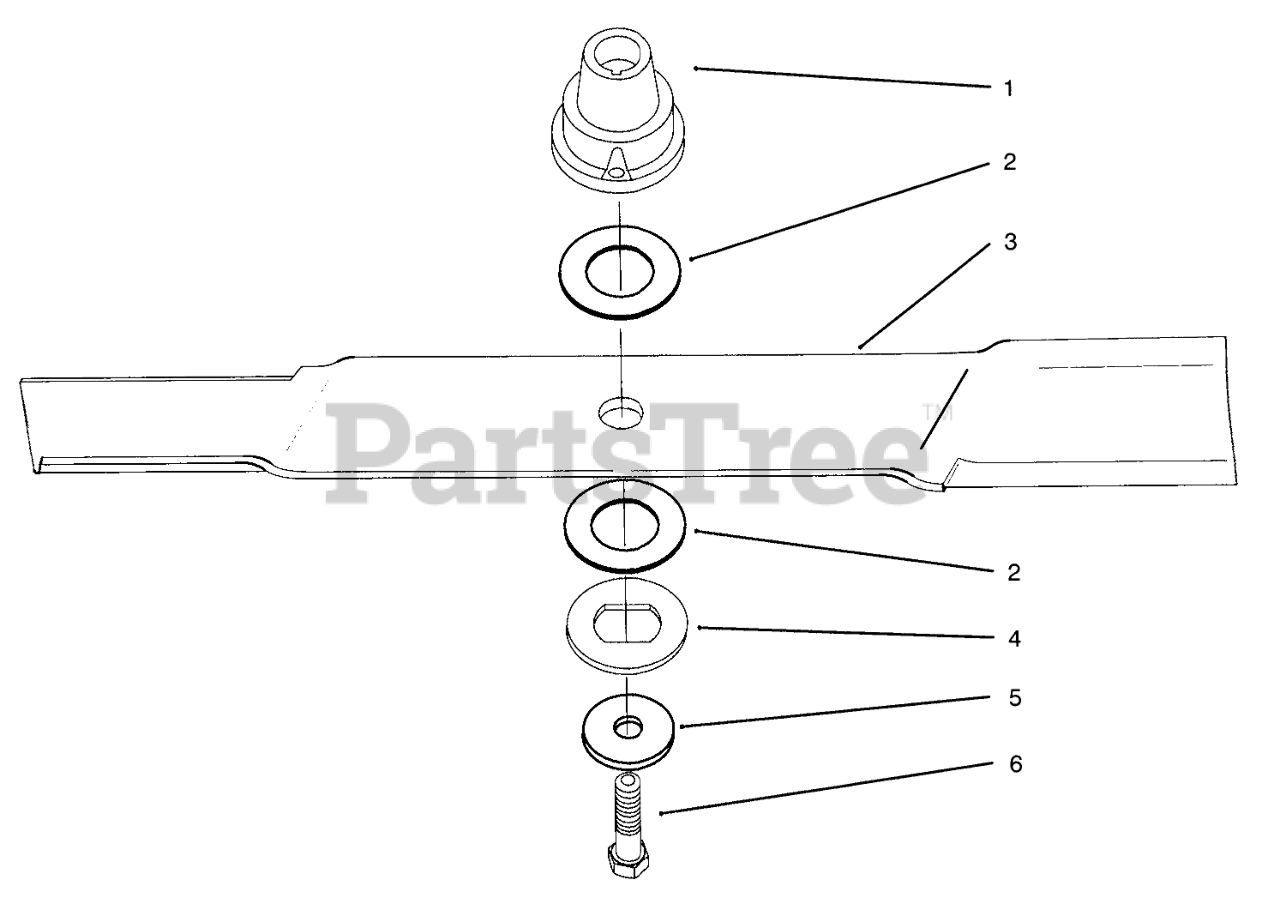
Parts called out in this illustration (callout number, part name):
1	RETAINER - BLADE
2	WASHER - FRICTION
3	BLADE - 43 CM
4	WASHER - PRESSURE
5	WASHER - SPRING
6	SCREW-BLADE
